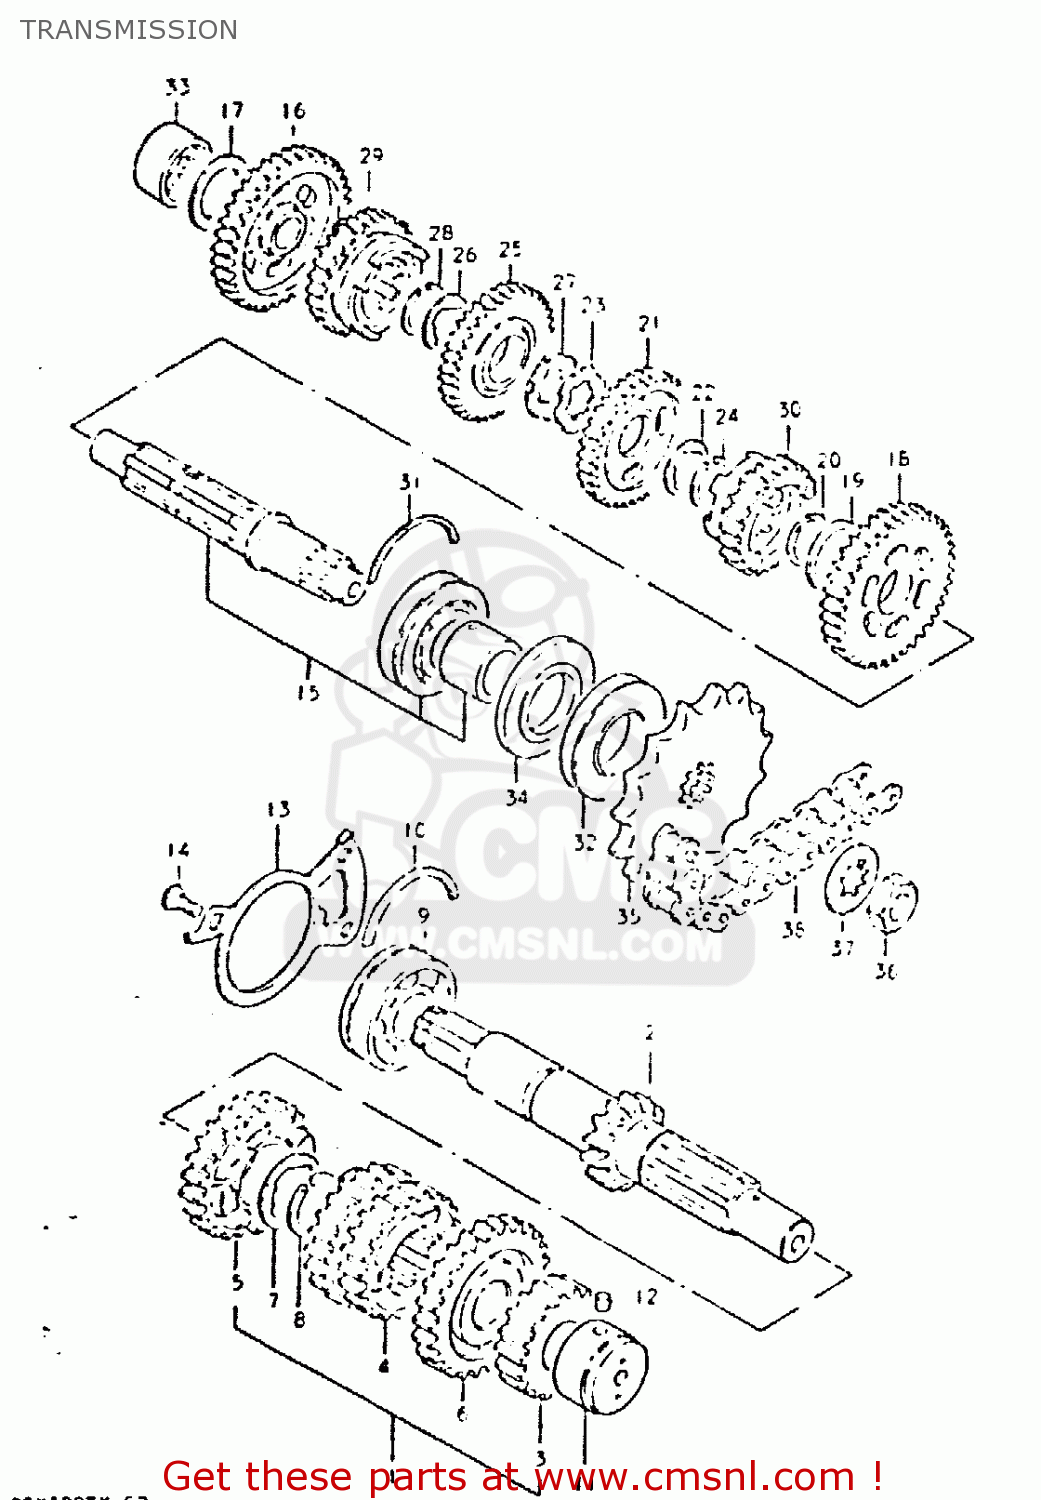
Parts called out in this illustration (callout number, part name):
1	SHAFT,COUNTER
2	SHAFT,COUNTER
3	GEAR,2ND DRIVE(NT:18)
4	GEAR,THIRD DRIVE
5	GEAR,FIFTH DRIVE
6	GEAR,SIXTH DRIVE
7	WASHER
8	CIRCLIP
9	BEARING(25X62X17)
10	C-RING
11	ROLLER BEARING (20X34X2
12	PIN
13	PLATE,COUNTERSHAFT BEARING
14	SCREW
15	SHAFT,DRIVE
16	GEAR,FIRST DRIVEN
17	WASHER
18	GEAR,SECOND DRIVEN
19	WASHER
20	CIRCLIP
21	GEAR,THIRD DRIVEN
22	WASHER,LOCK
23	WASHER,LOCK
24	CIRCLIP
25	GEAR,FOURTH DRIVEN
26	WASHER,LOCK
27	WASHER
28	CIRCLIP
29	GEAR,5TH DRIVEN(NT:25)
30	GEAR,SIXTH DRIVEN
31	C-RING
32	SEAL,OIL(32X62X7)
33	ROLLER BEARING (20X34X1
34	SEAL,OIL(32X62X5.5)
35	SPROCKET,ENGINE(NT:16)
36	NUT
37	WASHER
38	CHAIN ASSEMBLY,DRIVE
